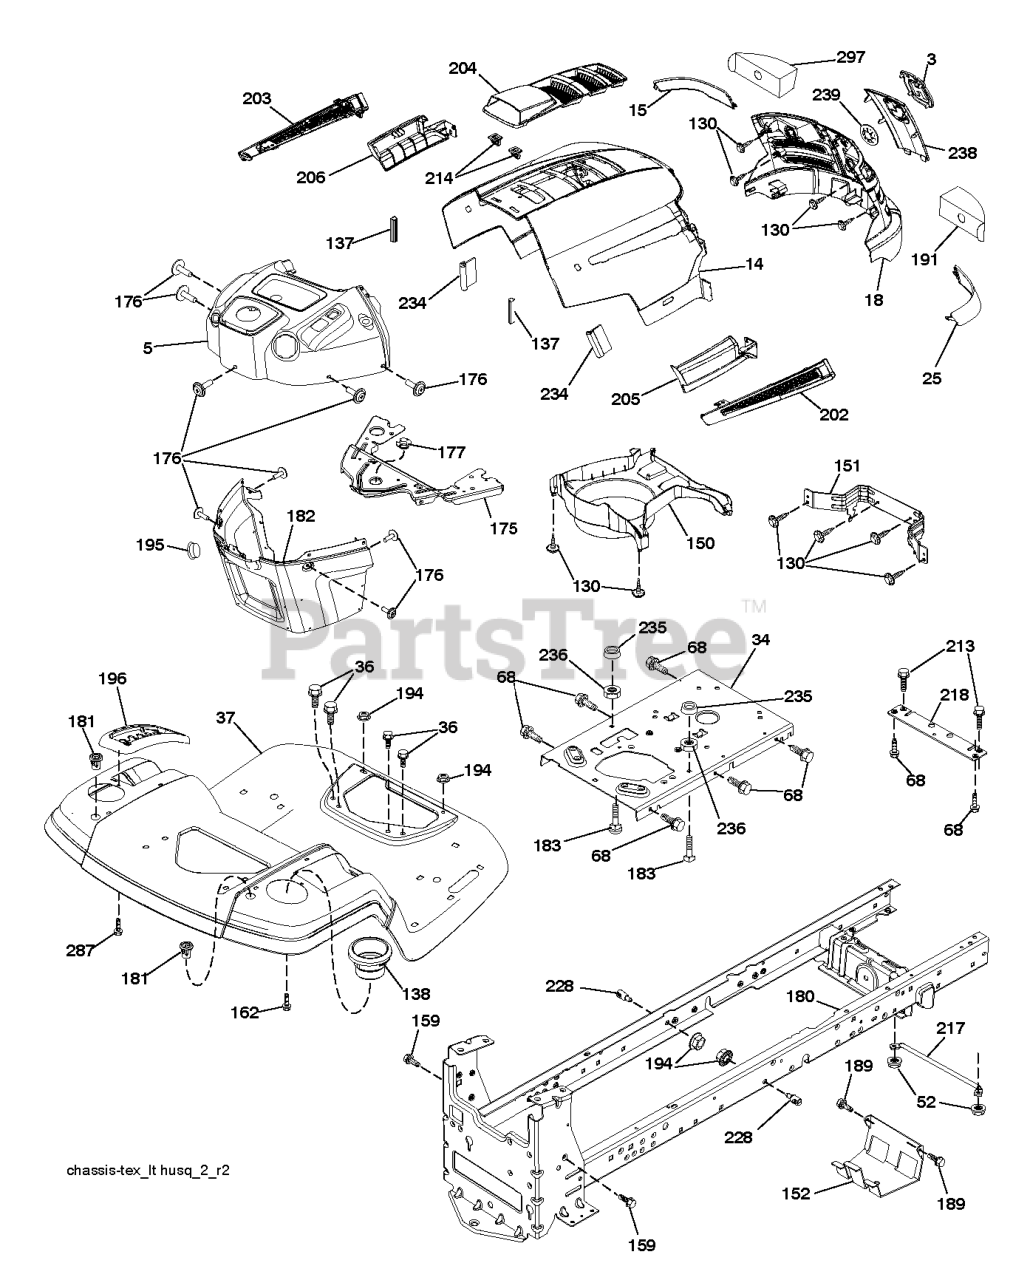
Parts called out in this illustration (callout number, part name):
3	RP LOGO
5	DASH
14	HOOD.HUSQVARNA.LT.ORANGE
15	LENS.HUSQVARNA LT.LH
18	GRILLE.SVC.HUSQVARNA.LT.GREY
25	LENS.HUSQVARNA LT.RH
34	PLATE.ENGINE.WELDED.CHASSIS
36	SCREW 5/16"
37	FENDER.TLT.FS.W/CUPHLD.ORANGE
52	LOCKNUT
68	Screw 5/16-18 x 1/2 Hex, Self Tapping 5/16-18 x 1/2
130	SCREW.#10 X 0.750.BOS
137	BUMPER DASH
138	CUPHOLDER.TL.TEX.418
151	BRACKET PIVOT
152	SHIELD.BROWNING.W/TEX
159	SCREW, 3/8-16X3/4
162	SCREW.HI-LO.CONSOLE
175	CROSSMEMBER
176	SCREW.#10-24X5/8.RN.QU
177	BUSHING STEERING
180	CHASSIS
181	BUSHING.MNT.FEND.CRGO.
182	DASH.LOWER.PREDATOR LT
183	BOLT.5/16-18X1-1/4 FULL THD
189	SCREW
191	INSERT.REFLECTIVE.RH.
194	NUT LOCK HEX FLANGE 5/16-18
195	PLUG DASH
196	RP CONSOLE.ASM.DECKLFT.GR/RBT.
204	VENT TOP HOOD
213	BOLT
214	CLIP.RETAINER.TINNER.
217	ROD.PIVOT.HOOD
218	X-PIECE.HOOD.STOP.NON/
228	STUD.FASTNER.W/ANTI-ROTATE
234	BUMPER.HOOD.TEX.HUSQVARNA
235	SPACER FENDER
236	NUT.CENTERLOCK.5/16-
238	TRIM
287	SCREW 1/4X20
297	INSERT REFLECTIVE
